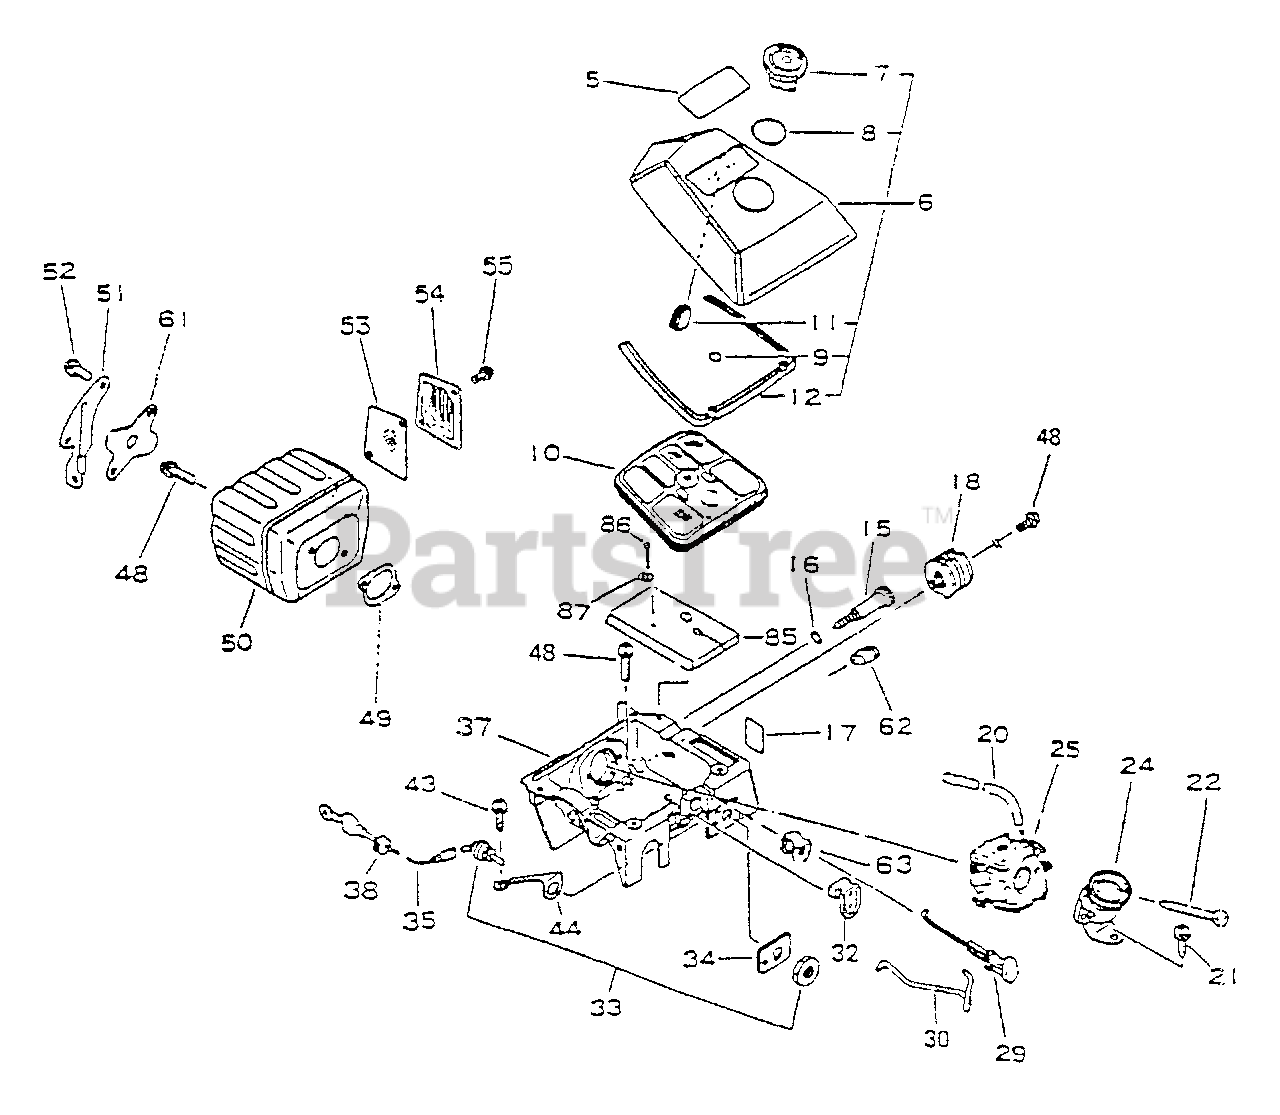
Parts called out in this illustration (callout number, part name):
5	LABEL - MODEL CS-6700
6	AIR FILTER COVER ASSY
7	THUMBSCREW
8	O-RING - 22
9	O-RING - 11
10	FILTER, AIR
12	SEAL
15	SCREW, IDLE ADJUST
16	O-RING - 7
17	LABEL - CAUTION
20	FUEL PIPE KIT
21	SCREW - 5X14
22	SCREW - 5X55
24	ADAPTOR, INTAKE
25	CARBURETOR HDA-76
29	ROD, CHOKE
30	ROD, THROTTLE
32	ROD, THROTTLE
33	IGNITION SWITCH ASSY
34	LABEL - STOP
35	LEAD - GROUND
37	CASE, CARBURETOR
43	SCREW - 5X20
44	TERMINAL - GROUND
48	SCREW - 5X20
49	GASKET, EXHAUST
50	MUFFLER
51	BRACKET, MUFFLER
52	SCREW - 5X14
53	SCREEN, SPARK ARRESTOR
54	GUIDE, EXHAUST
55	SCREW - 4X10
61	COVER, MUFFLER
63	GROMMET
86	PIN, SPLIT - 3X18
